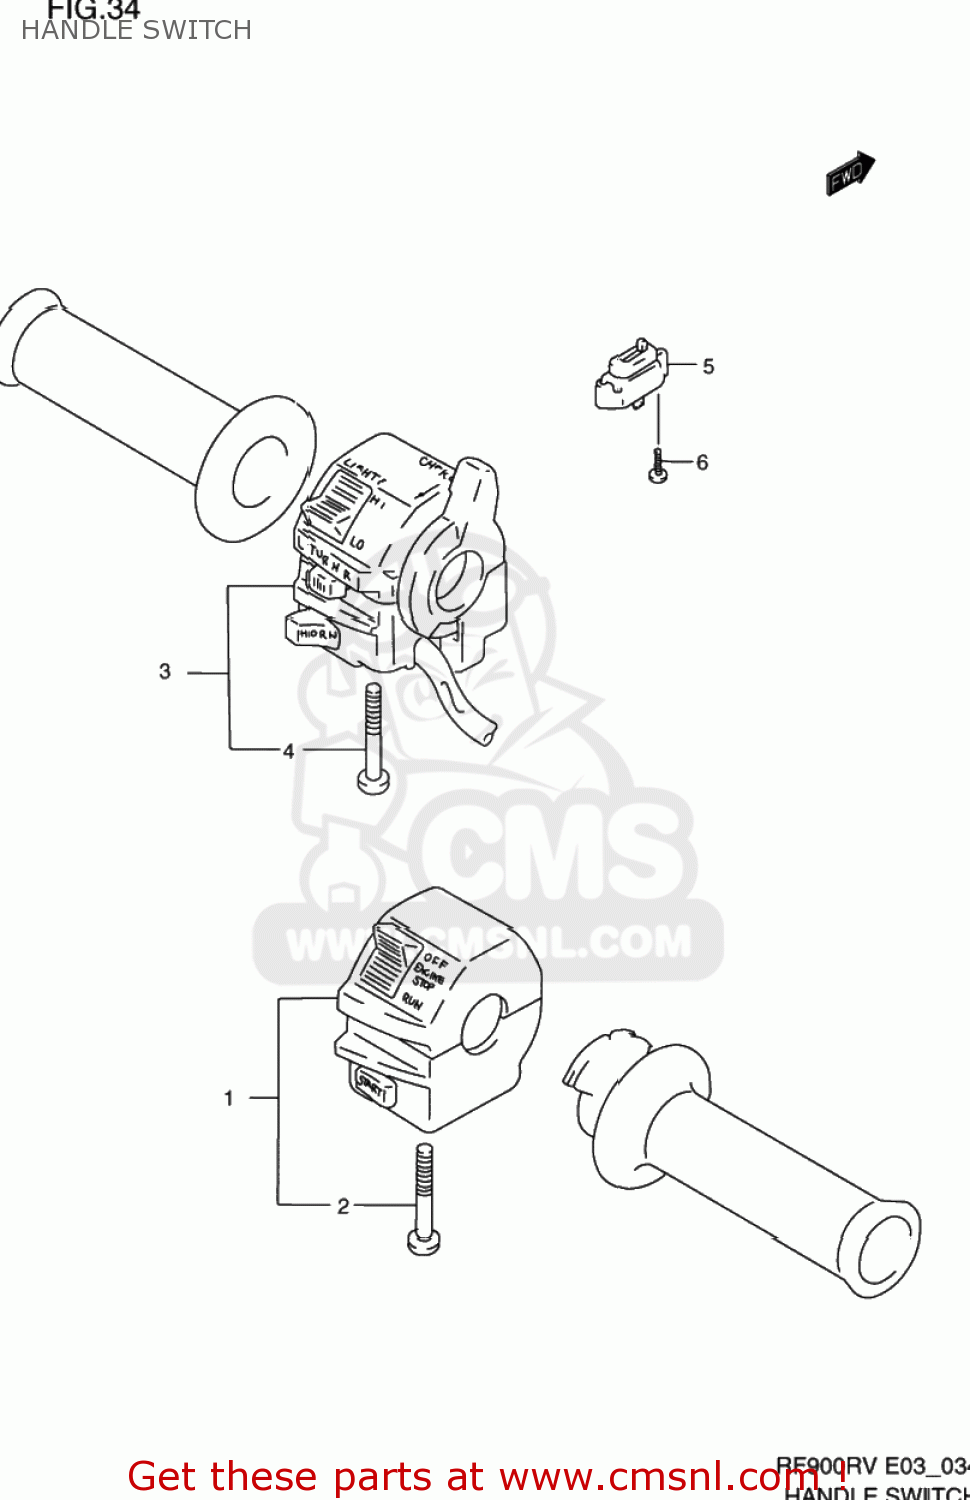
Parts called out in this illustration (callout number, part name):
1	SWITCH ASSEMBLY,HANDLE,RIGHT
2	SCREW, 5X45
3	SWITCH ASSY,HANDLE,L
4	SCREW, 5X45
5	SWITCH ASSY,CLUTCH
6	SCREW
